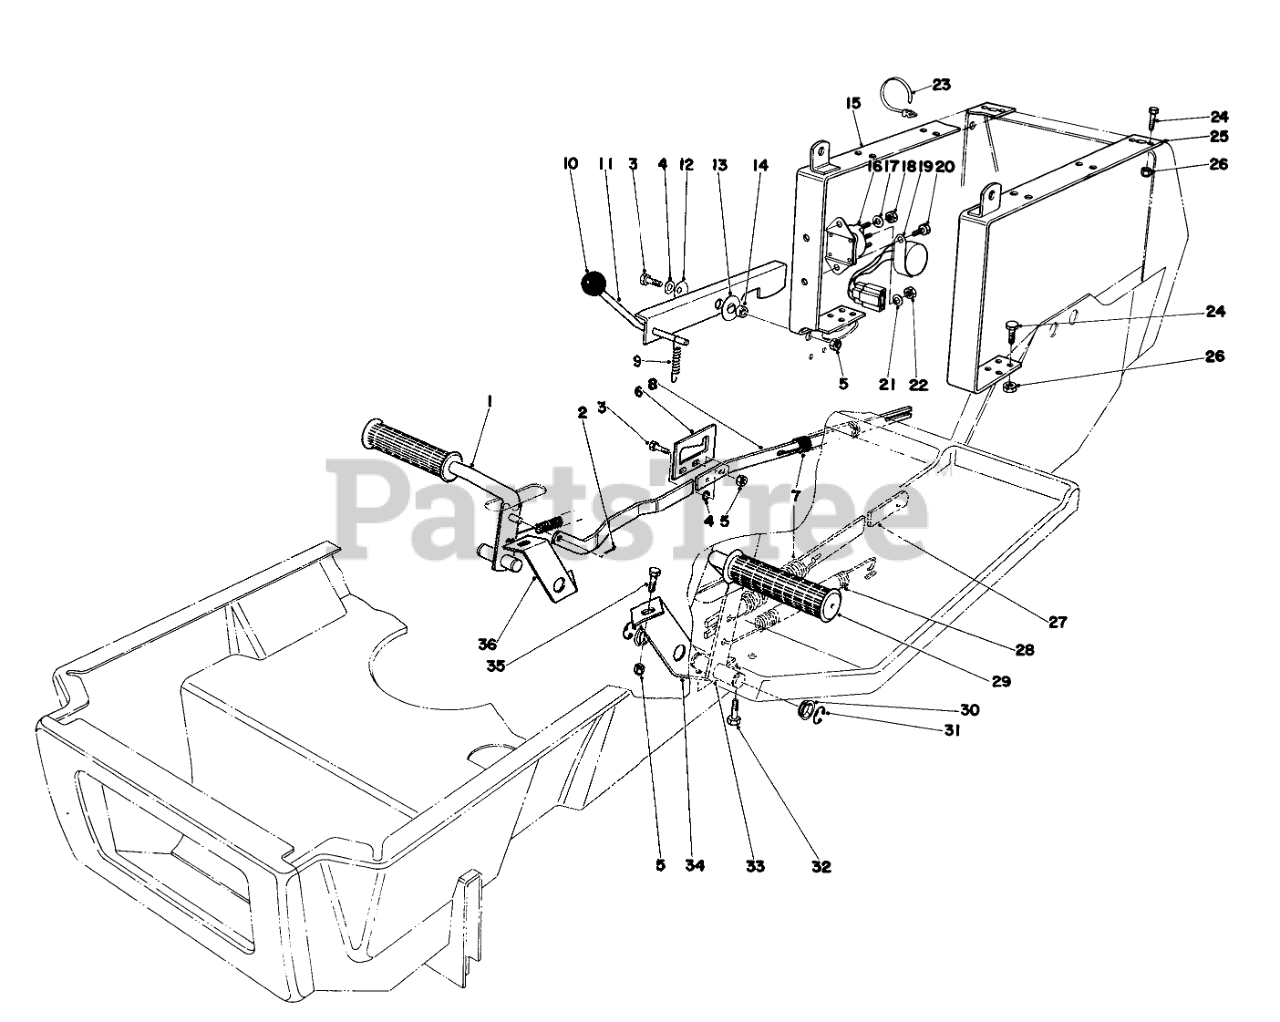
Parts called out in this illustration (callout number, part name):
1	BRAKE PEDAL WA BO
2	PIN-COTTER
3	SCREW-HH
4	WASHER-PLAIN
5	NUT-LOCK, CONE
6	LATCH PLT-BRAKE ROD
7	EXT SPRING O
8	LINK BRAKE ROD WAB
9	CONT ROD SPRING 0
11	PARKING BRAKE WA B
12	Belleville Washer
13	WASHER-PLASTIC
14	SPACER
15	RR BODY STRAP WA B
16	SOLENOID
17	WASHER-LOCK
18	NUT-JAM, BRASS
19	Module Interlock
20	SCREW-HWH
21	WASHER-LOCK
22	NUT-HEX
23	TIE-MOUNT, PUSH
24	SCREW-HH
25	LH RR BODY STRAP WA B
26	NUT-LOCK, CONE
27	CLUTCH ROD LINK B
28	SPRING-EXTENSION
29	FOOT PAD
30	Nyliner
31	E-RING
32	SCREW-HWHTF
33	CLUTCH PEDAL WA BO
34	LH PEDAL SUPT B
35	SCREW-HH
36	RH PEDAL SUPT B
